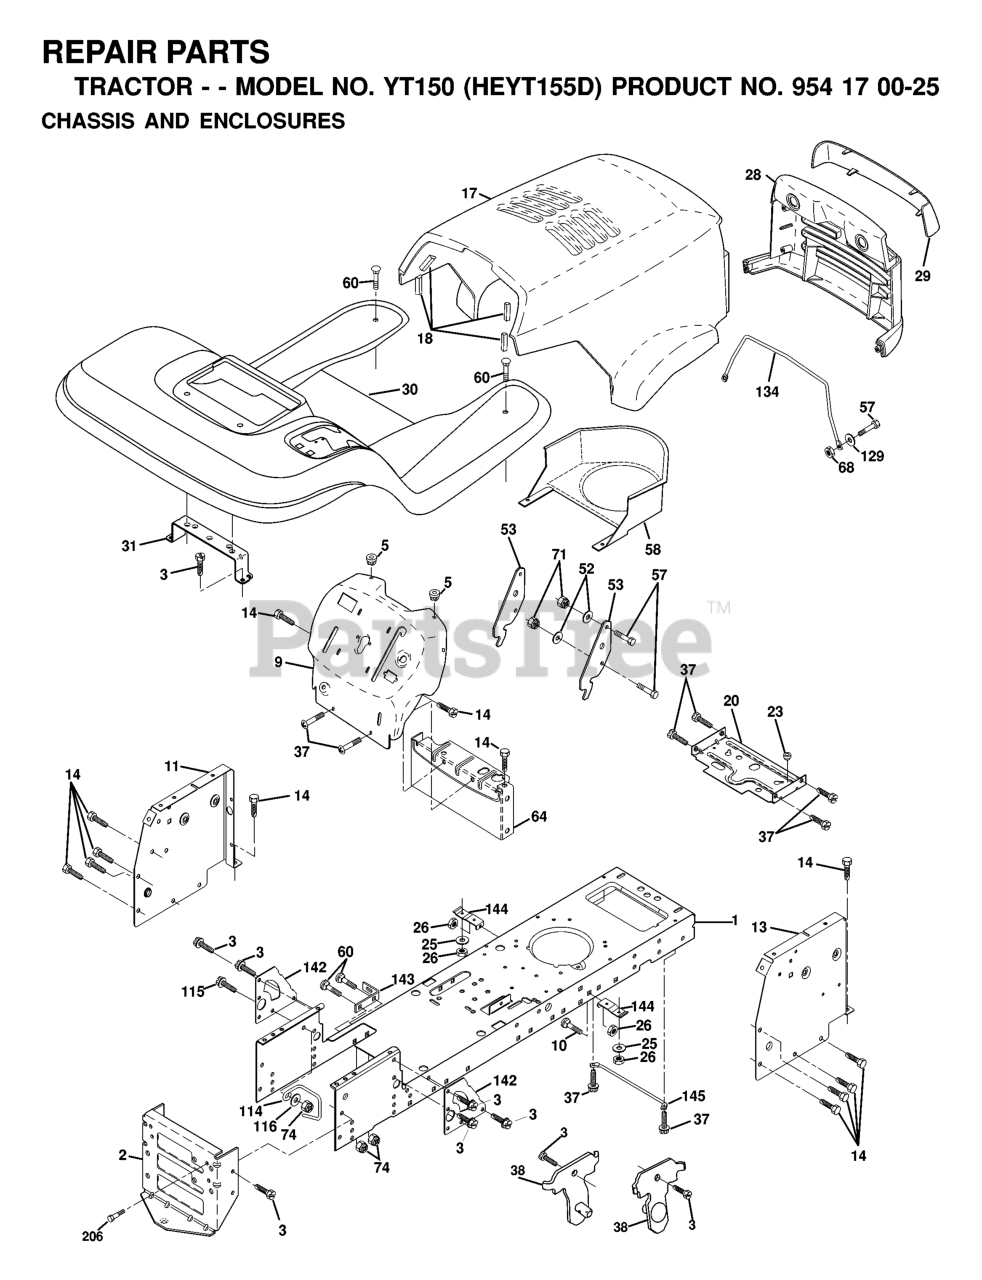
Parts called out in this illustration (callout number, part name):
1	RP.CONTROL.THROTTLE.47.W/Z.BEN
2	GRIP.1X5.06
3	CLIP.RETAINER.CABLE.BZP
4	SCREW.TORX.#10-14X1/2
6	CONSOLE.GREY.W/THROT.TR530
10	GRIP T
11	RETAINER M
12	SHOULDER BOLT ST
13	HANDLE.SHIFT.TILLER.498
14	GROMMET.RUBBER.CRT.TILLER
15	ROD SHIFT RT UNIVERSAL
16	BOLT D
17	LOCK.HANDLE.CRT
19	WASHER CRT
20	LEVER.LOCK.CRT
21	HANDLE.ASM.HUSQ/P.PRO.GREY
23	TAPPING SCREW
24	CLIP.PLATED
27	NUT T
31	BOLT.PIVOT
42	SCREW.#10 X 0.750.BOS
43	CABLE.HANDLE.TINE.CONT.CE
44	CONTROL.HANDLE.TWO.FUNCTION.CE
45	SCREW.#10 X 0.500
46	LOCK HANDLE
